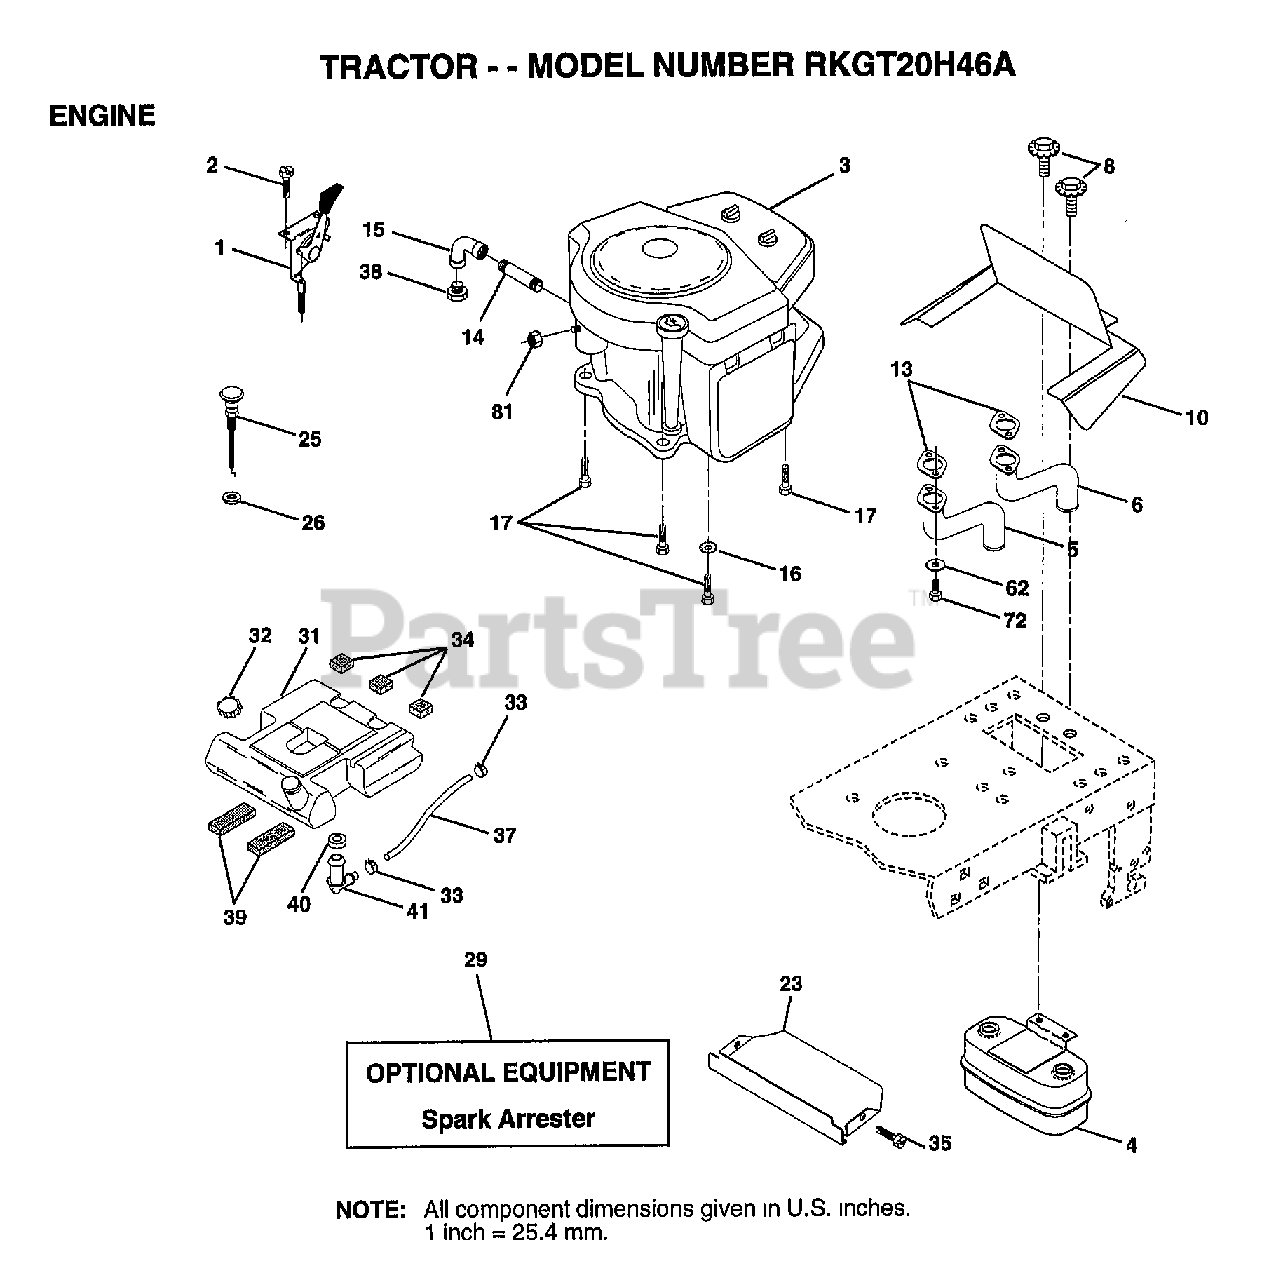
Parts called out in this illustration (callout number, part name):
1	CONTROL.TRTL.37
2	SCREW LT
4	MUFFLER.TW.LOTONE
5	TUBE MANIFOLD LH
6	TUBE MANIFOLD RH
8	BOLT.5/16-18.UNC
10	SHIELD.BROWNING
14	PIPE NIPPLE LT
15	ELBOW
16	LOCKWASHER
17	SCREW LT
23	SHIELD.BRN/DBR.GD
25	"CONTROL.CHOKE.40""BLK"
26	"NUT,KEPS 3/8-24IM"
31	TANK FUEL REAR
32	CAP ASM FUEL
33	HOSE CLAMP
34	PAD-SPACER LT
35	SCREW
37	FUEL LINE T
39	PAD IDLER TI
40	BUSHING OUTLET T
41	STEM.TANK.FUEL
62	LOCKWASHER
72	SCREW
81	NUT
